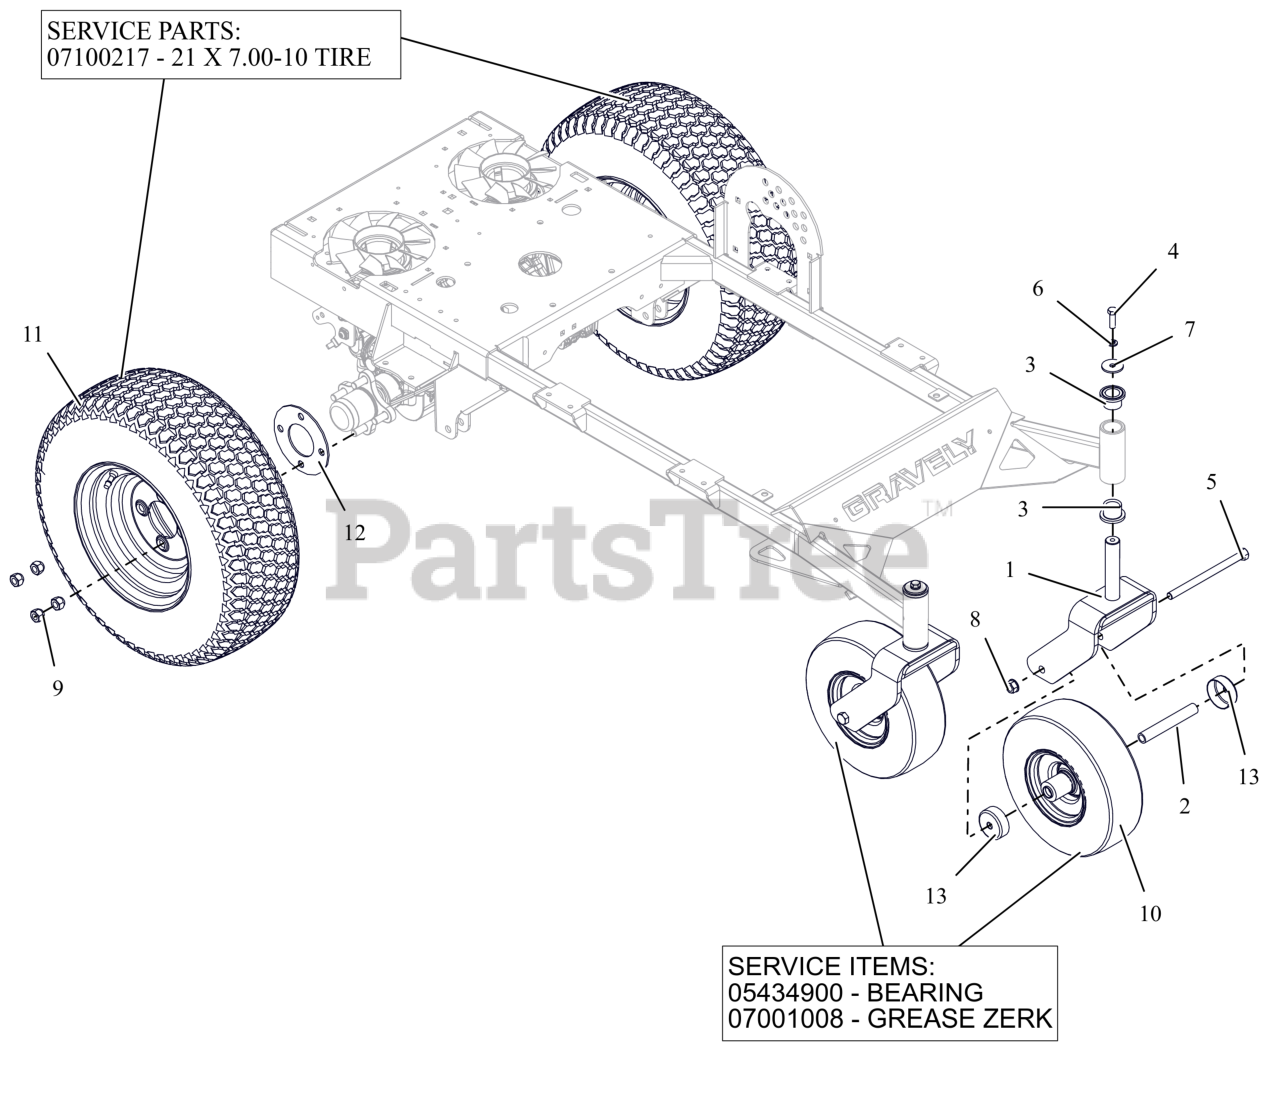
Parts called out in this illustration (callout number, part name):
1	WLDMT, CASTER FORK (RED)
2	SPACER, ROLLED WHEEL
3	BRG, FLG 1.00 X 1.25 X 1.00
4	BLT, HEX .38-16X1.25 G5 ZCC
5	BLT, HEX 0.5-13X7 GR5 ZCC
6	WSHR,LK-REG .375X.094 ZCC
7	WSHR, FLT .380X1.50X.125 ZCC
8	NUT-LK-CTR-FLG .500-13 GG ZCC
9	NUT, WHEEL .50-20 ZCC
10	ASM, WHL/TIRE 11X4.00-5
10	BRG-BALL .752X1.380X.500
10	GREASE FITTING 1/4-28 EXTENDED
11	ASSY, TIRE/WHL 21X7.00-10
11	TIRE, 21X7.00-10
12	SPACER, WHEEL 4-BOLT
13	SHIELD, WHEEL BEARING
